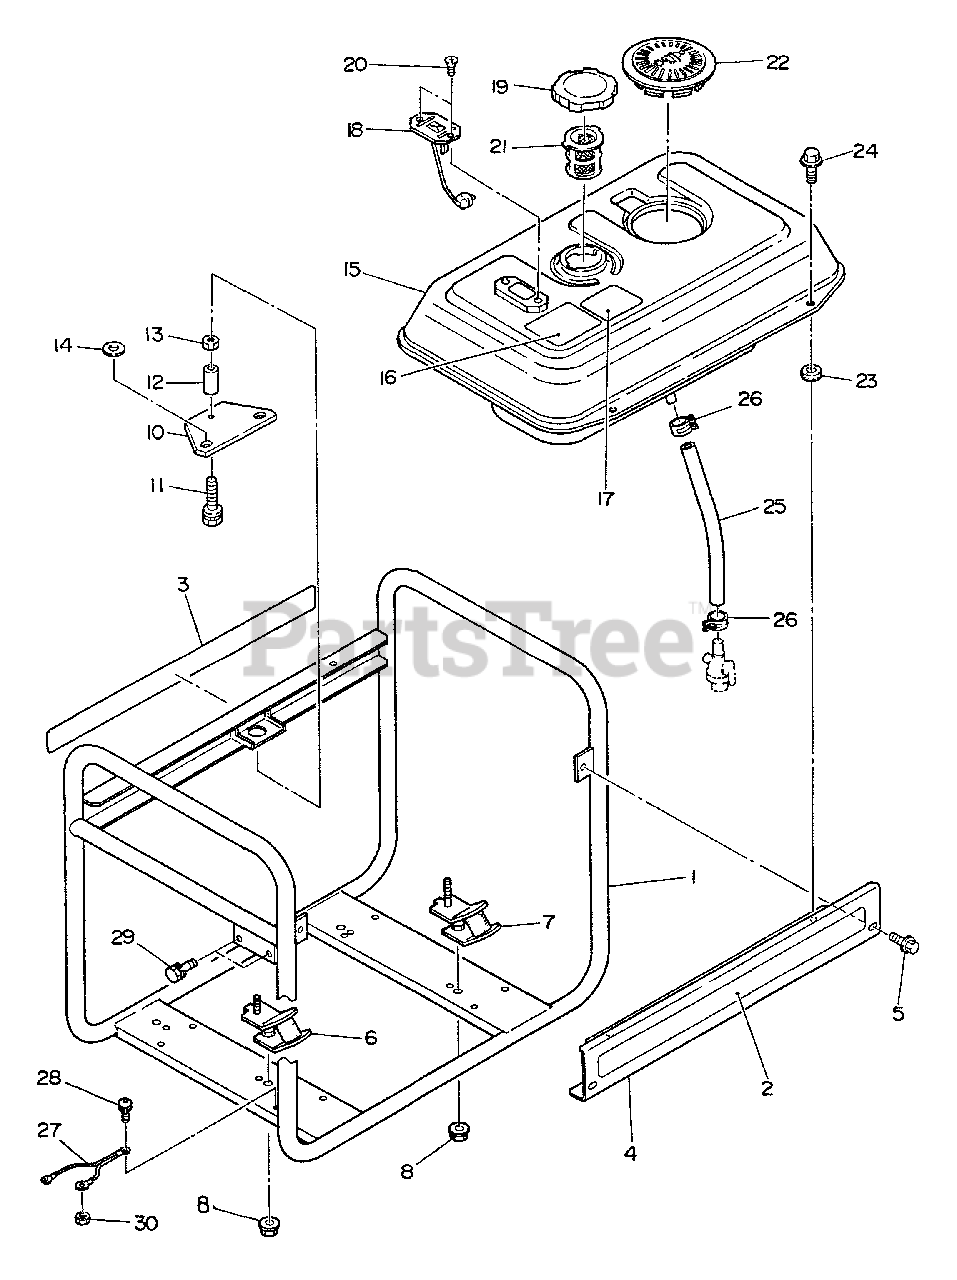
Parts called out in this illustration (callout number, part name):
1	PIPE FRAME ASSY
2	LABEL - MODEL EG-3501
3	LABEL - MODEL EG-3501
4	SIDE PLATE ASSY
5	BOLT - FLANGE
6	MOUNT, RUBBER
7	MOUNT, RUBBER
8	NUT - 8 -- FLANGE
10	STOPPER PLATE
11	BOLT
12	SPACER
13	NUT
14	WASHER
15	FUEL TANK ASSY
16	LABEL - CAUTION -- OPERATION
17	LABEL - DANGER
18	LEVEL ASSY
20	SCREW
21	FILTER, FUEL
22	COVER
23	WASHER - RUBBER
24	BOLT - FLANGE
25	RUBBER PIPE (11.5 X 17.5 X 230mm)
26	CLAMP, HOSE
27	LEAD - GROUND
28	SCREW
29	BOLT
30	NUT
